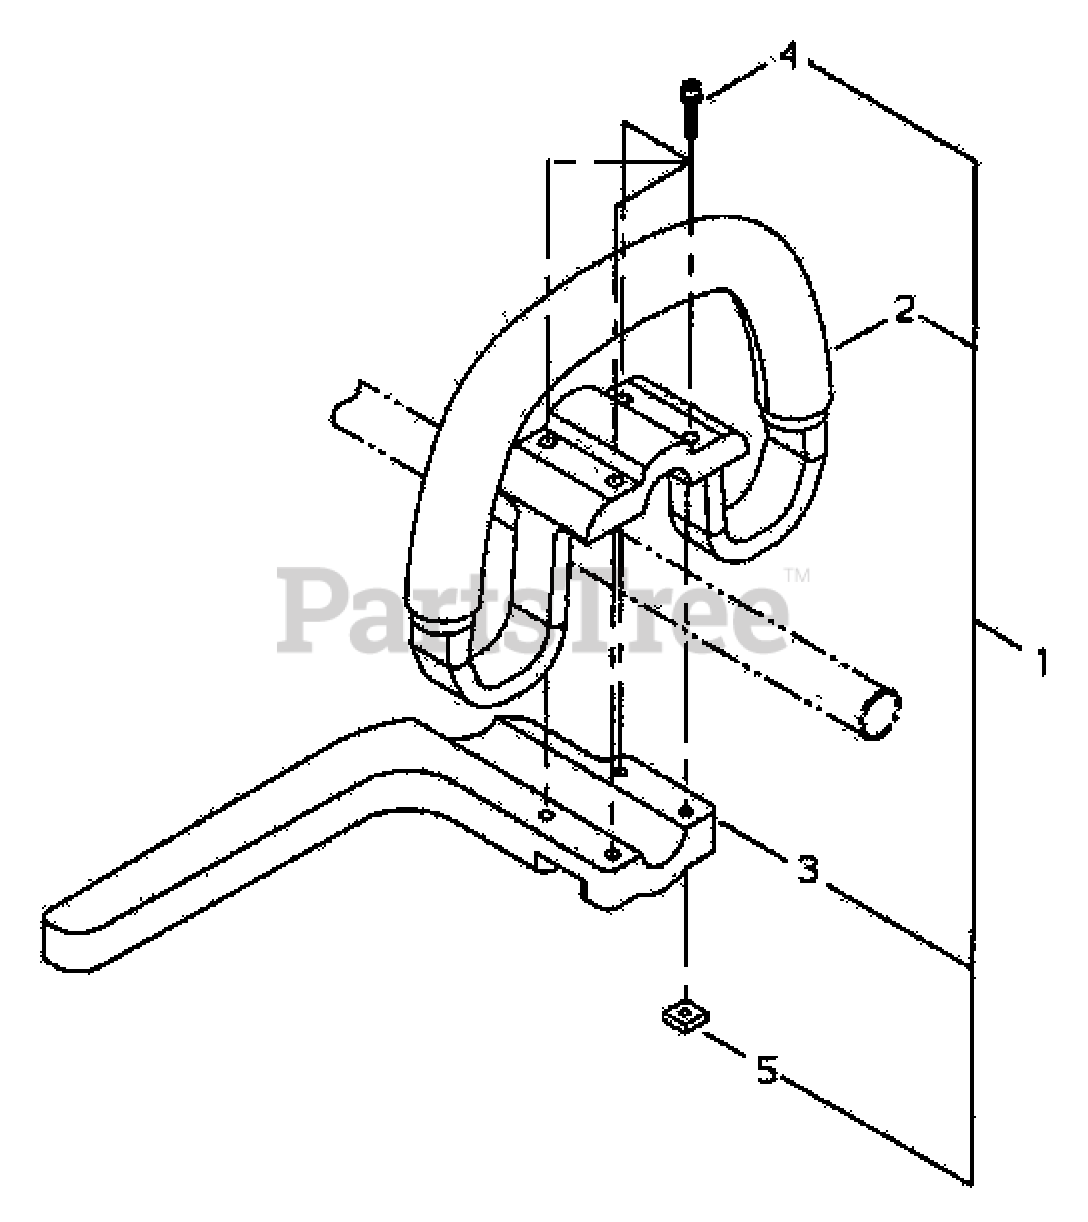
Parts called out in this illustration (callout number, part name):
1	HANDLE ASSY
2	HANDLE
3	BAR, BARRIER
4	BOLT M5×35
5	NUT M5
